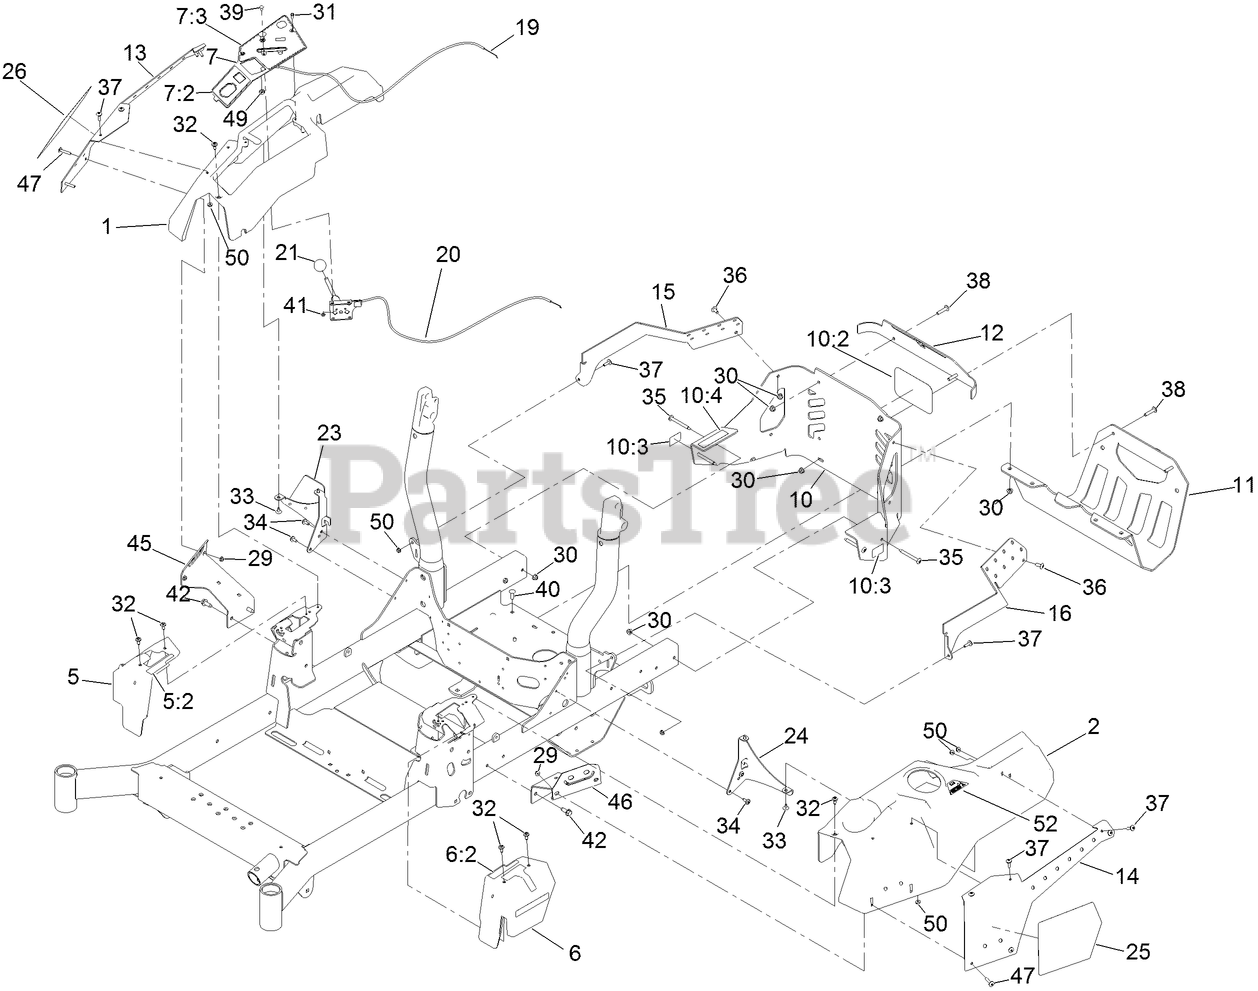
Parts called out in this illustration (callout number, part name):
1	CONSOLE-RH
2	CONSOLE-LH
5	COVER-CONTROL, MOTION (RH)
5:2	DECAL-CONTROL, MOTION (RH)
6	COVER-CONTROL, MOTION (LH)
6:2	DECAL-CONTROL, MOTION (LH)
7	CONTROL PANEL ASM
7:2	DECAL-PANEL, CONTROL
7:3	DECAL-PANEL, CONTROL
10	REAR GUARD ASM
10:2	DECAL
10:3	DECAL-WARNING
10:4	DECAL-ARRESTOR, SPARK
11	GUARD-MUFFLER
12	TRIM-UPPER REAR
13	COVER,POD RH
14	COVER [BLACK]
15	BRACKET-GUARD, RH
16	BRACKET-GUARD, LH
19	CABLE-CONTROL, CHOKE
20	CABLE-CONTROL, THROTTLE
21	KNOB-BALL
23	SUPPORT-CONSOLE, RH
24	BRACKET-CONSOLE, LH
25	DECAL - HDX
26	DECAL - HDX
29	NUT-HF
30	NUT-HF, NI
31	SCREW-HWH
32	SCREW-SHOULDER
33	SCREW-TORX
34	SCREW-TORX
35	SCREW-TORX
36	SCREW-TORX
37	SCREW-TRUSS
38	SCREW-TORX
39	BOLT-CARR
40	SCREW-CARR
41	NUT-LOCK, NI
42	SCREW-FORMING, THREAD
45	BRACKET-SUPPORT, POD (RH)
46	BRACKET-SUPPORT, POD (LH)
47	SCREW-TRUSS
49	NUT-HJ
50	NUT-KEPS
52	DECAL-FILL, FUEL
